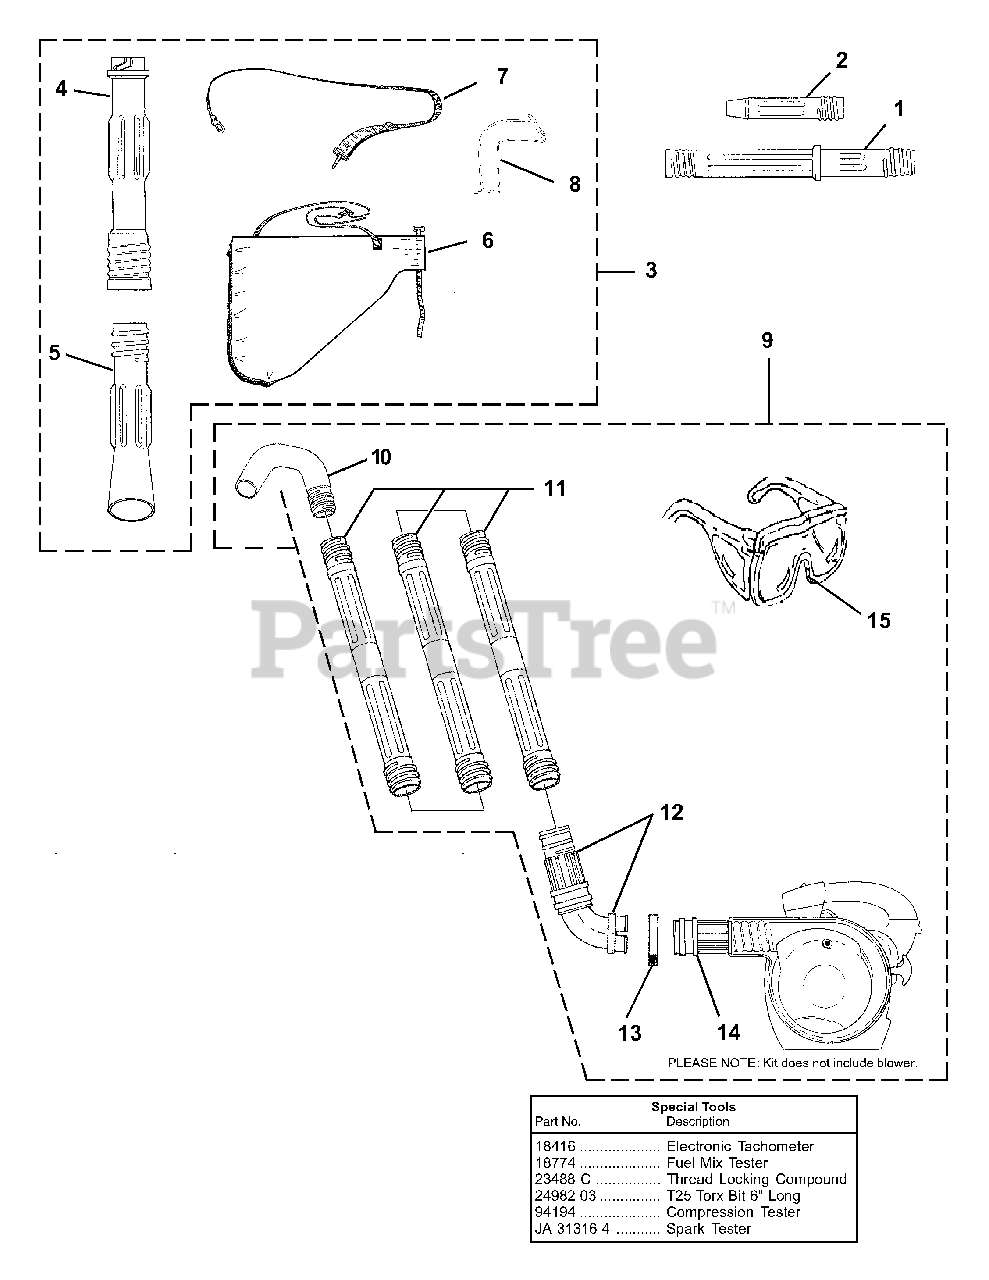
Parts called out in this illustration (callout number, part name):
1	Tube, Blower
2	Nozzle, Blower
3	Vacuum Kit
4	Vac Tube, Upper
5	Vac Tube, Lower
7	Shoulder Strap
8	Air Deflector
9	Gutter Maintenance Kit
10	Full Elbow
11	Straight Tube
12	Upper Elbow & Swivel Adapter
13	Large Clamp
14	Adapter, Gutter
15	Safety Glasses - Clear
